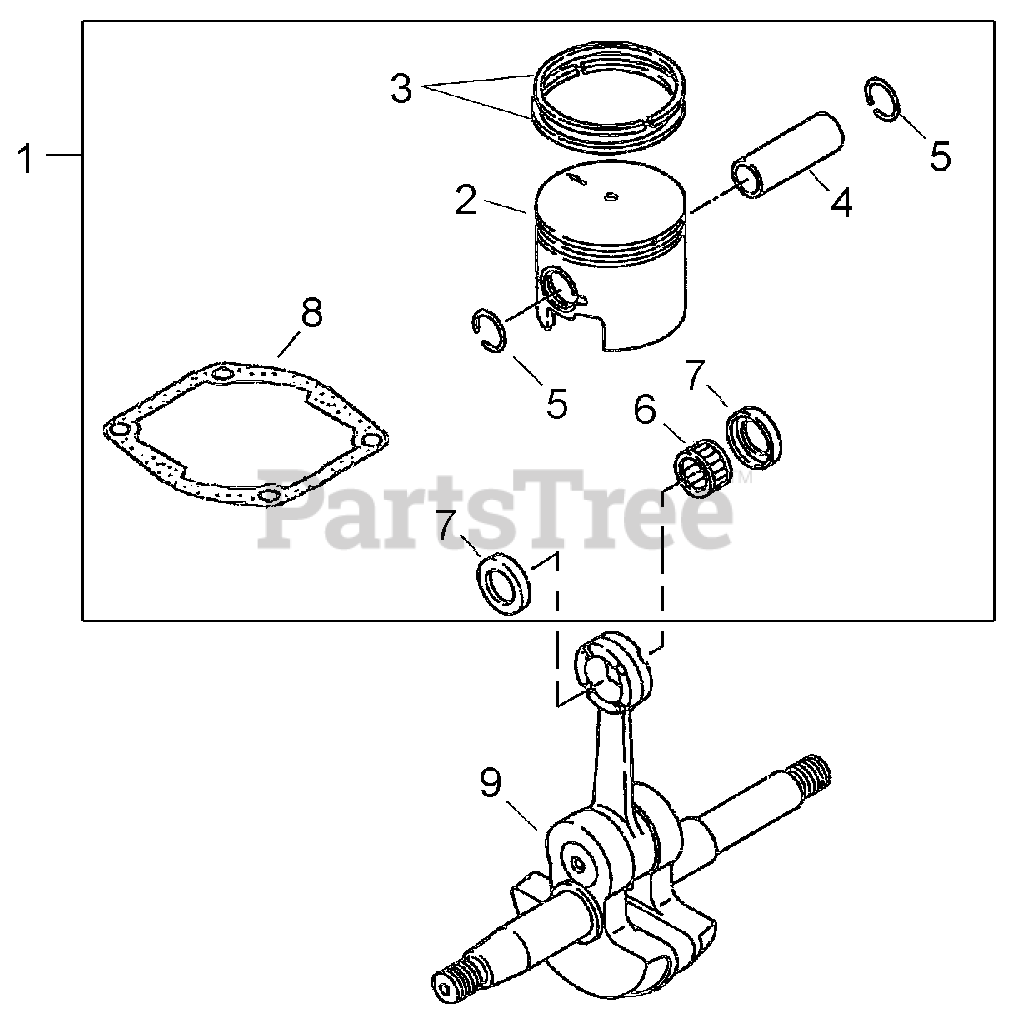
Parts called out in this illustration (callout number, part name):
1	PISTON KIT
2	PISTON
3	RING, PISTON
4	PIN, PISTON
5	RING, RETAINING
6	BEARING, NEEDLE - 10
7	SPACER
8	GASKET, CYLINDER
9	CRANKSHAFT ASSY
